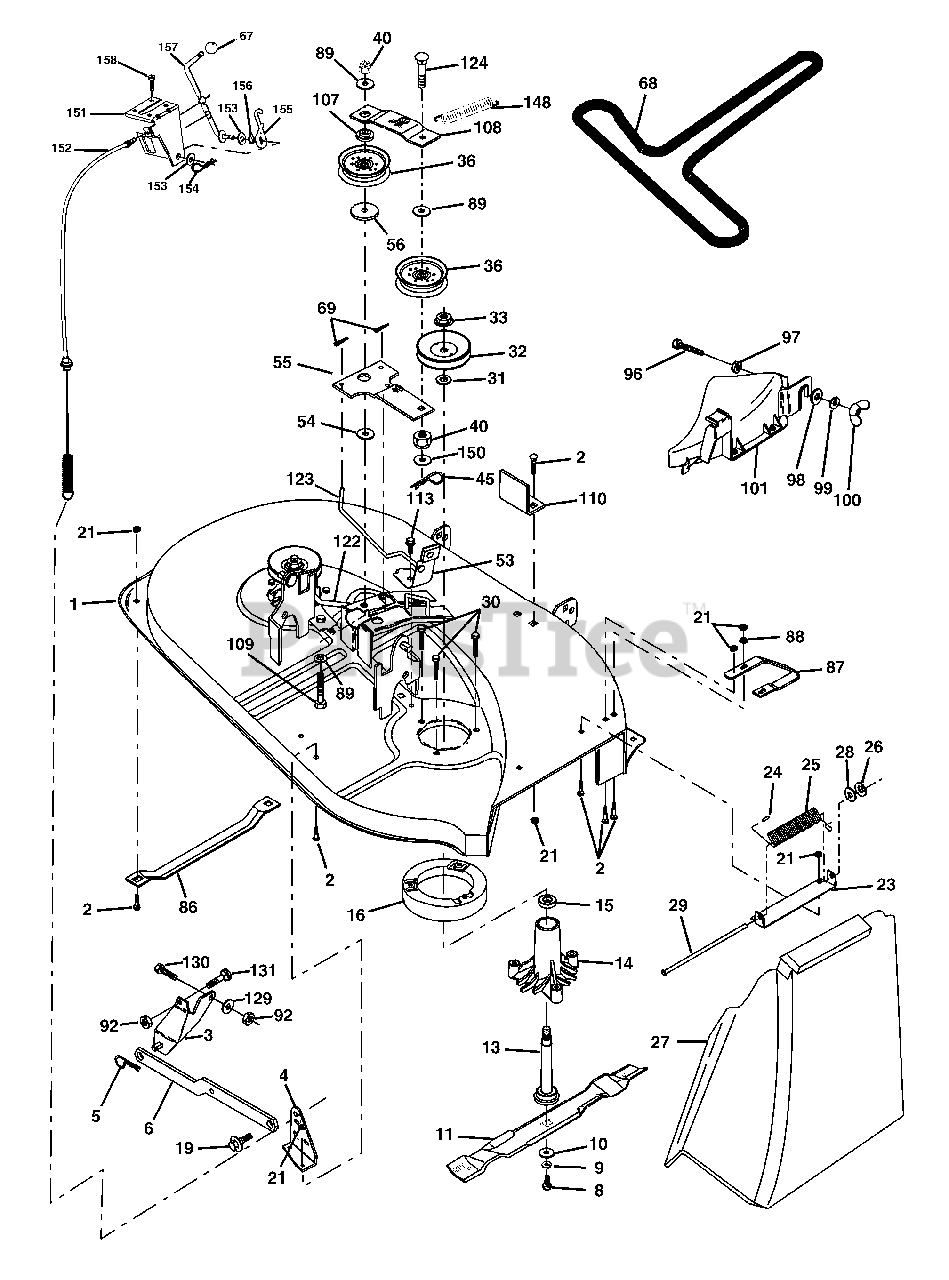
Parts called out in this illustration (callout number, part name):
1	Mower Deck Assembly
2	Bolt
3	Bracket Assembly,Sway Bar
4	Bracket Sway Bar
5	Retainer Spring
6	Bar Sway Deck
8	Bolt, Hex 3/8-24 x 1.25 Gr. 8
9	Washer, Lock Hvy Hlcl 3/8
10	Washer, Hardened
11	Blade, 38" Mulching Std
11	Blade, 38" Mulching Premium
11	Blade, 38" Hi'Lift
13	Shaft Assembly, Mandrel, Vented
14	Housing, Mandrel, Vented
15	Bearing, Ball, Mandrel
16	Stripper, Mower Deck
19	Bolt, Shoulder
21	Nut Crownlock 5/16-18
23	Bracket, Mower Deflector
24	Cap, Sleeve
25	Spring, Torsion, Deflector
27	Shield, Deflector
28	Washer 11/32 x 5/8 x 16 Ga.
29	Rod, Hinge
30	Screw Thdrol Hex
31	Washer, Spacer
32	Pulley, Mandrel
33	Nut, Toplock, Flanged
36	Pulley, Idler, Flat
40	Nut Crownlock 3/8-16
45	Retainer, Spring
53	Brake Assembly
54	Washer, Hardened
55	Idler Arm Assembly
56	Spacer, Retainer
67	Knob RD 3/8-16 Plstc Thd
69	Pin, Cotter 3/32 x 3/4
86	Runner LH
88	Washer 11/32 x 3/4 x 16 Ga.
89	Washer 13/32 x 1 x 12 Ga
92	Nut Lock Hex 3/8-16
96	Nut Centerlock 3/8-16 unc
97	Bolt 3/8-16 x 1-1/4
98	Washer 13/32 x 1-1/4 x 16 Ga.
99	Washer Lock 3/8
101	Cover Asm. Mulching
107	Spacer, Retainer
108	Stiffener, Idler Arm
109	Bolt Hex Fin 3/8-16 Unc x 2-1/2
110	Upstop Deck Front
113	Screw Thdrol 5/16-18 x 3/4
122	Rod, Brake, LH
123	Rod, Brake, RH
129	Washer 13/32 x 13/16 x 12 Ga.
130	Bolt Fin Hex 3/8-16 x 1.0
131	Bolt RDHD 3/8-16 x 1
146	Bolt Carriage Idler
148	Spring Return Idler
149	Retainer Spring Yellow Zinc
150	Washer 9/32 x 3/4 x 16 Ga.
151	Bracket Clutch
152	Cable Clutch
153	Washer Flat 3/8" Type B
154	Spring Retainer
155	Spring Retention Lever
157	Rod Clutch
158	Screw Hex Thd Cut 1/4-20 x 1/2
